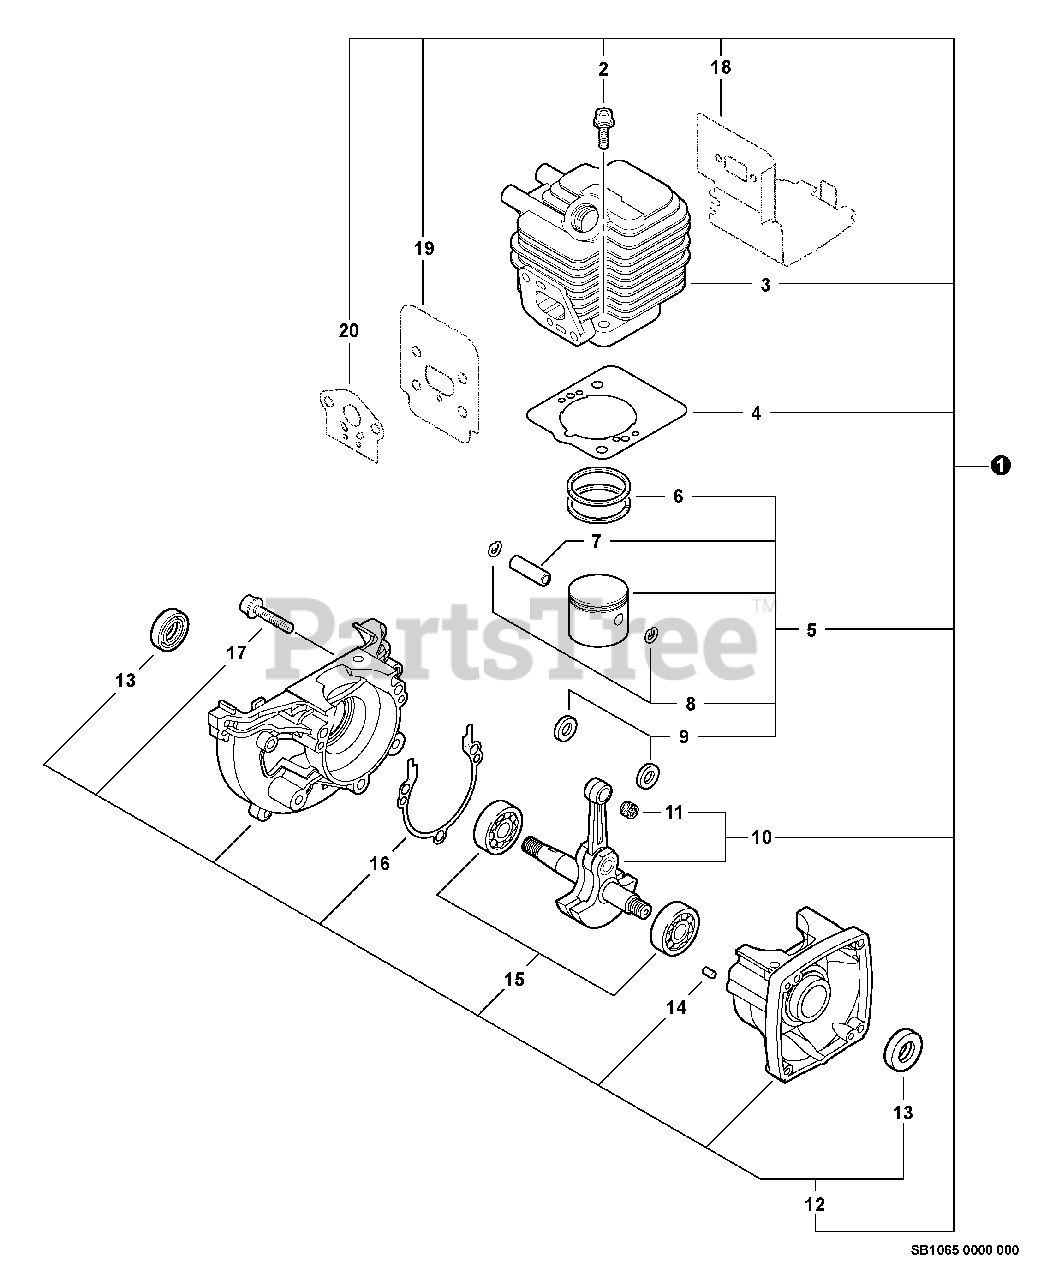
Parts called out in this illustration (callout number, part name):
1	SHORT BLOCK -- SB1065
2	SCREW - 5X22
3	CYLINDER
4	GASKET, CYLINDER
5	PISTON KIT
6	RING, PISTON
7	PIN, PISTON
8	RING, RETAINING
9	SPACER, PISTON
10	CRANKSHAFT ASSY
11	BEARING, NEEDLE - 8
12	CRANKCASE KIT
13	SEAL, OIL
14	PIN - LOCATING
15	BEARING, BALL - 6201
16	GASKET, CRANKCASE
17	SCREW - 5X28
18	SHIELD, EXHAUST
19	SHIELD, INTAKE
20	GASKET, INTAKE
